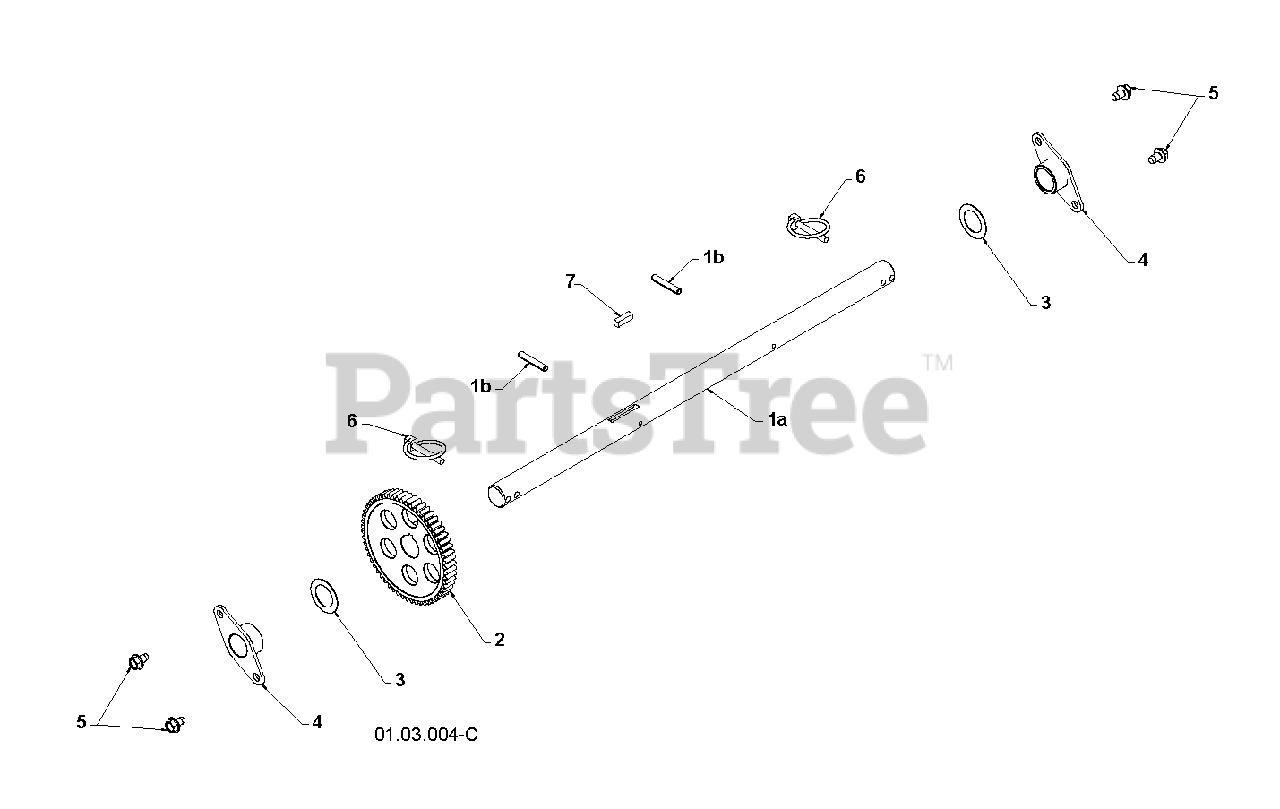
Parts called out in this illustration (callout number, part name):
1	AXLE.SHAFT.ASM.W/ROLPIN.NON-PS
2	SPROCKET.WELDMENT.AXLE.1.00
3	WASHER 1.00
4	BEARING, AXLE
5	SCREW LT
6	RIVET
7	KEY, SQUARE 1/4 X .875
8	RETAINER M
